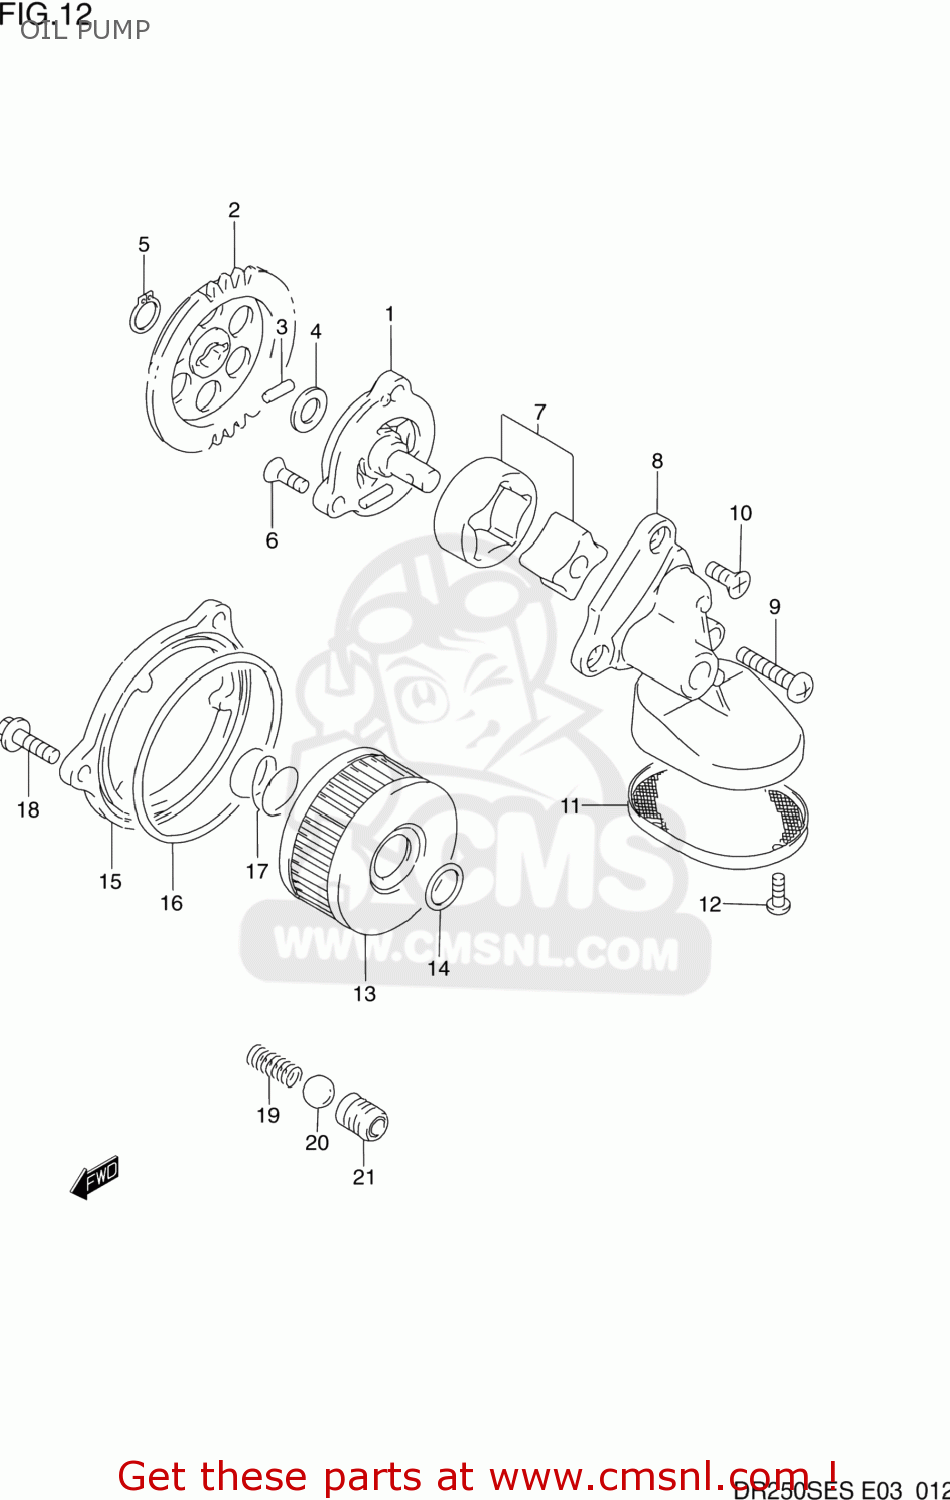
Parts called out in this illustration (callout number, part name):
1	PUMP ASSY,ENGINE OIL NO.1
2	GEAR,OIL PUMP DRIVEN
3	PIN(4X15.8)
4	SHIM
5	CIRCLIP,10MM
6	SCREW ,6X16
7	ROTOR SET,OIL PUMP,NO.2
8	COVER,OIL PUMP NO.2
9	SCREW,6X30
10	SCREW ,6X16
11	STRAINER,OIL PUMP NO.2
12	SCREW
13	FILTER ASSY,ENGINE OIL
14	O RING(D:2.4,ID:15.8)
15	CAP,OIL FILTER
16	O RING(D:2.4,ID:73)
17	SPRING
18	BOLT
19	SPRING
20	BALL
21	SEAT,OIL CHECK VALVE
